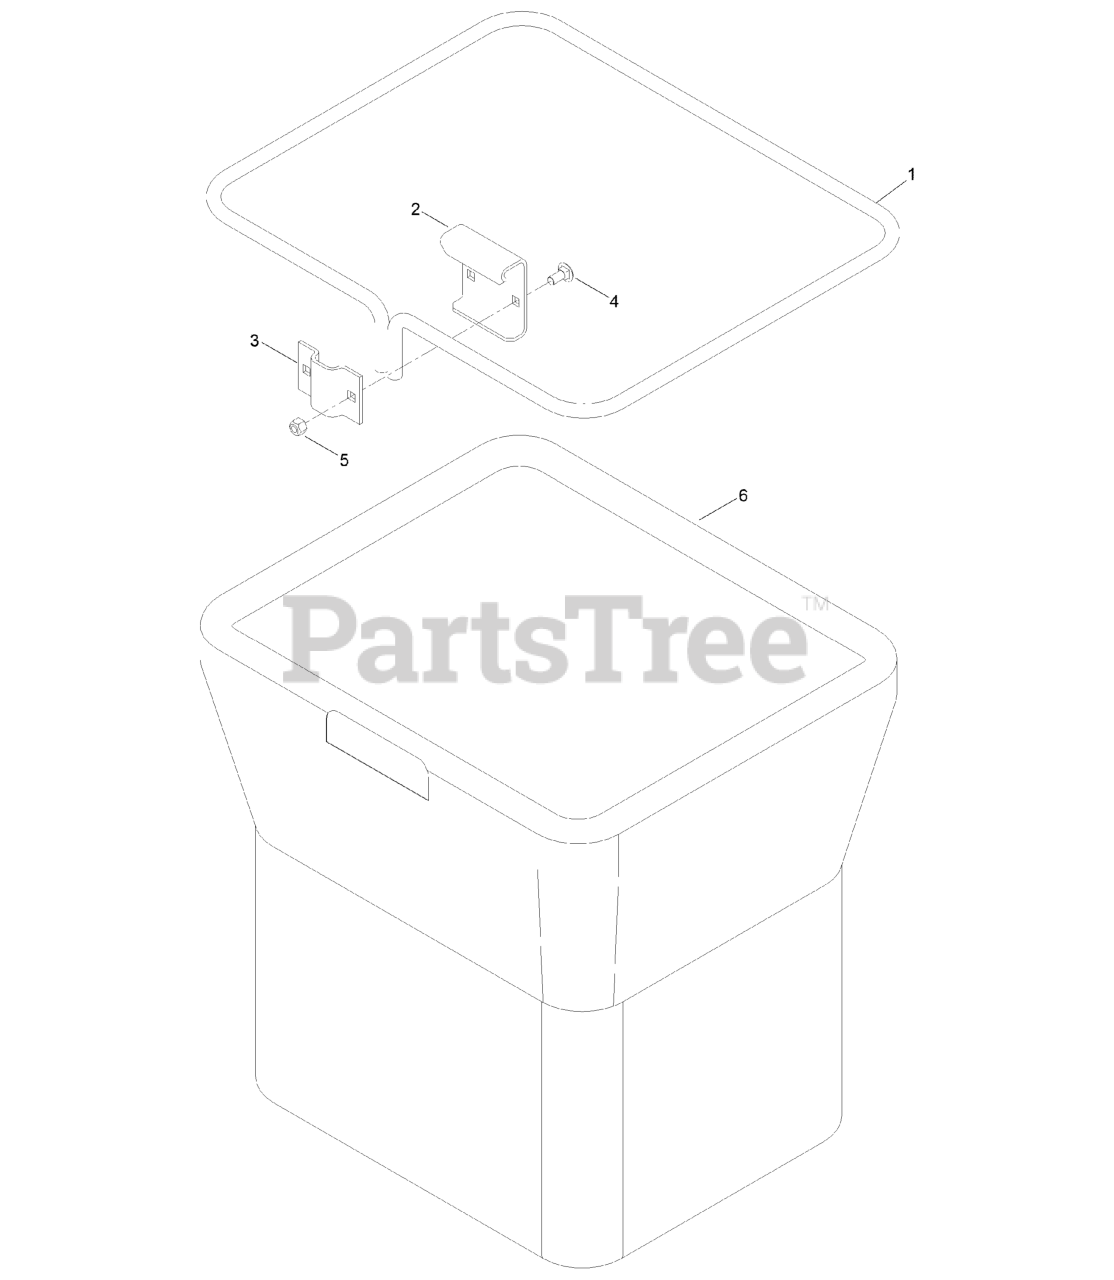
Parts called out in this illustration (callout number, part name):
1	FRAME-BAG
2	HANGER-BAG
4	BOLT-CARR
5	NUT-LOCK, NI
